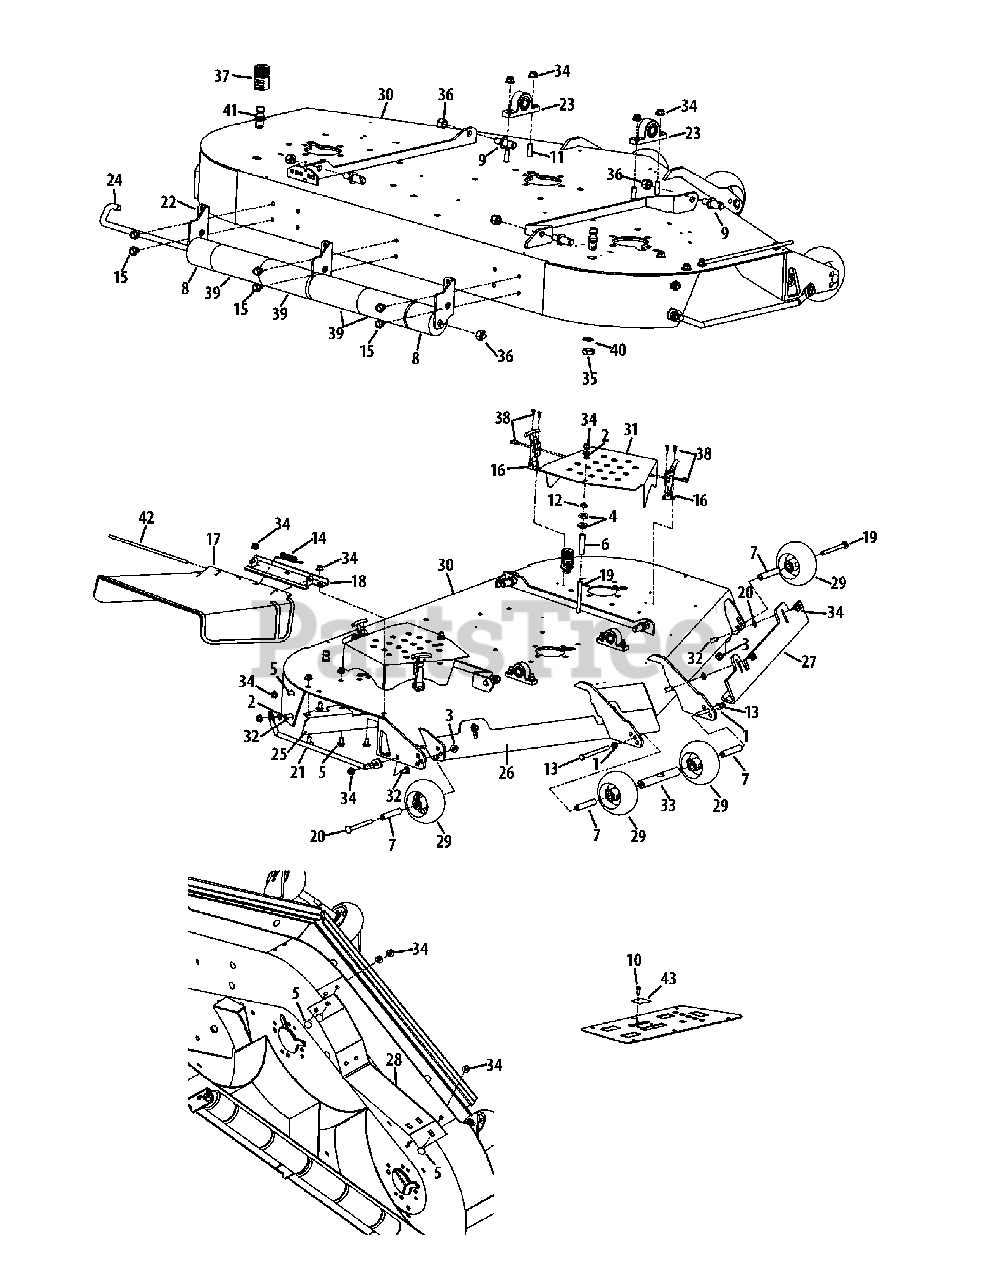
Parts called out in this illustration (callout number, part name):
1	Lock Washer, .375 x .680 x .100
2	Washer, .406 x .813 x .063
3	Flange Counter Lock Nut, 3/8-16
4	Washer, .390 x 1.00 x .180
5	Carriage Bolt, 3/8-16 x .75
6	Spacer, .400 x .560 x 2.45
7	Spacer, .390 x .620 x 3.04
8	Grass Catcher Frame Roller
9	Pin, 5/8 x 1.20
10	Flange Screw, #10-24 x .500
11	Carriage Bolt, 3/8-16 x 1.25
12	Jam Nut, 3/8-16
13	Hex Screw, 3/8-16 x 4.50
14	Torsion Spring, 0.639 x 2.16
15	Flange Screw, 3/8-16 x .500
16	T-Handle Draw Latch
17	Chute Deflector
18	Chute Deflector Bracket
19	Carriage Bolt, 3/8-16 x 4.00
20	Push Nut, .335 x .780 x .015
21	Finger Guard
22	Right Roller Mount Bracket
23	Steel Pillow Bearing
26	RH Front Adjustable Skirt
27	LH Front Adjustable Skirt
28	Adjustable Baffle
30	Deck Assembly
32	Carriage Bolt, 3/8-16 x 1.00
33	Ball Wheel Frount Mount Shaft
34	Flange Lock Nut, 3/8-16
35	Hex Nut, M16-1.5
36	Hex Lock Nut, 1/2-13
37	Water Nozzle Adapter
38	Rivet, 3/16
39	Front roller
40	Lock Washer, 17 x 23.8 x 1.95
41	Water Deck Nozzle
42	Chute Deflector Rod
43	Throttle Control Bracket
